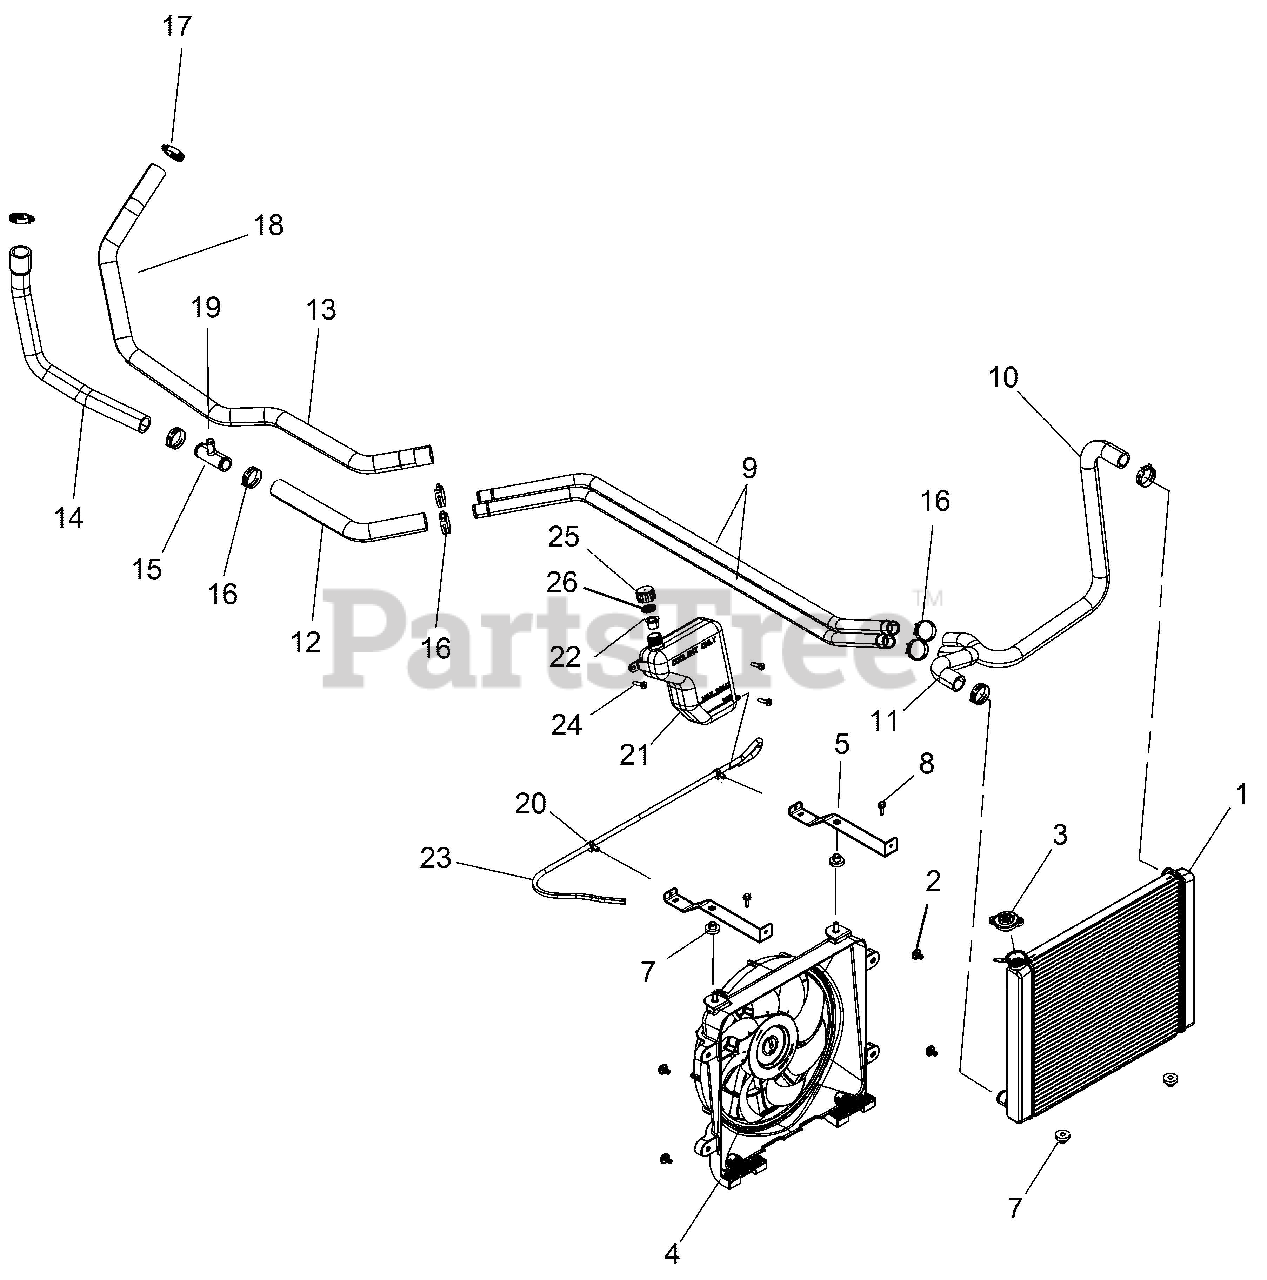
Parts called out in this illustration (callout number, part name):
1	ASM-RADIATOR,CORE
2	BOLT-M6X15MM
4	FAN-ASSEMBLY
5	MOUNT, RADIATOR, BLACK
8	SCR-M6X1.0X20,HXHD,FLG,TDFM,BL
9	TUBE-COOLANT,1"
10	HOSE-UPPER,RAD
11	HOSE-LOWER,RAD
12	HOSE, ENGINE, IN
13	HOSE, ENGINE, OUT
14	HOSE, ENGINE, BYPASS
15	CONNECTOR-TEE,1X1X0.5
16	CLAMP,SPRINGBAND 35/12,BLK
17	CLAMP-HOSE(WORM DR)25-40MM
18	CLIP-ROUTING
19	CLAMP-HOSE,SPRING,20MM
21	TANK-SURGE
22	CAP,PLUG9X(GRN),FLEX TEMP(10)
23	FUEL LINE-95 CENTIMETERS
24	SCR-#14X1 HI/LO-PH-PN TRX-M
25	CAP, OVERFLOW
26	SHROUD-RADIATOR,FRONT,BLK
